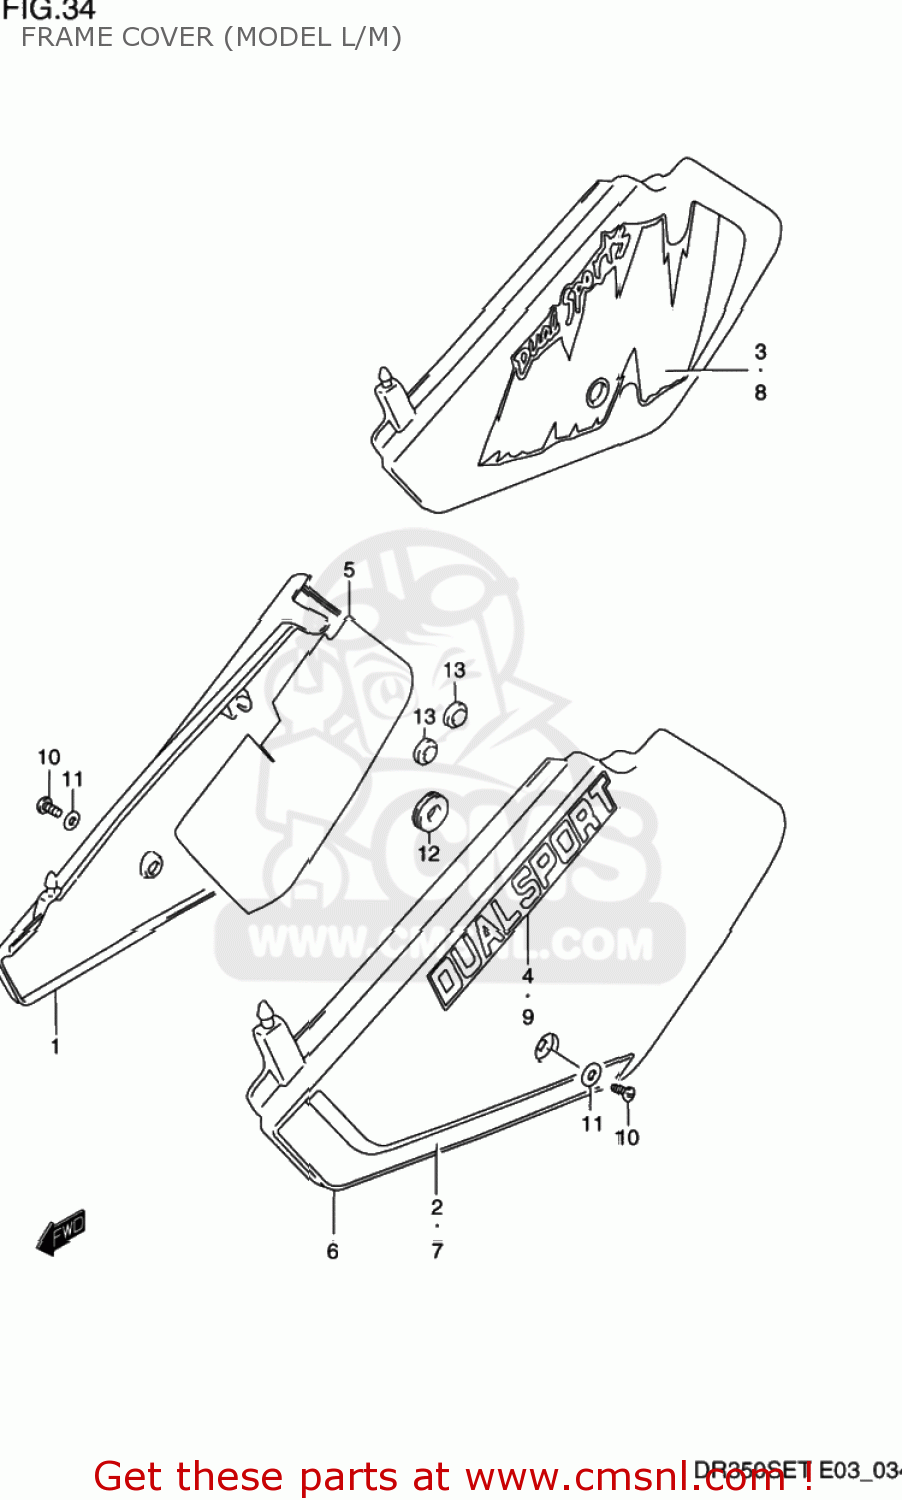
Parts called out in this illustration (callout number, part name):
1	COVER,FRAME,R(WHITE)
2	TAPE,FRAME COVER,RIGHT
3	TAPE,FRAME COVER,RIGHT
4	EMBLEM,FRAME COVER
5	SHIELD,FRAME COVER,R
6	COVER,FRAME,L(WHITE)
7	TAPE,FRAME COVER,LEFT
8	TAPE,FRAME COVER
9	EMBLEM,FRAME COVER
10	SCREW
11	WASHER
12	CUSHION
13	CUSHION
